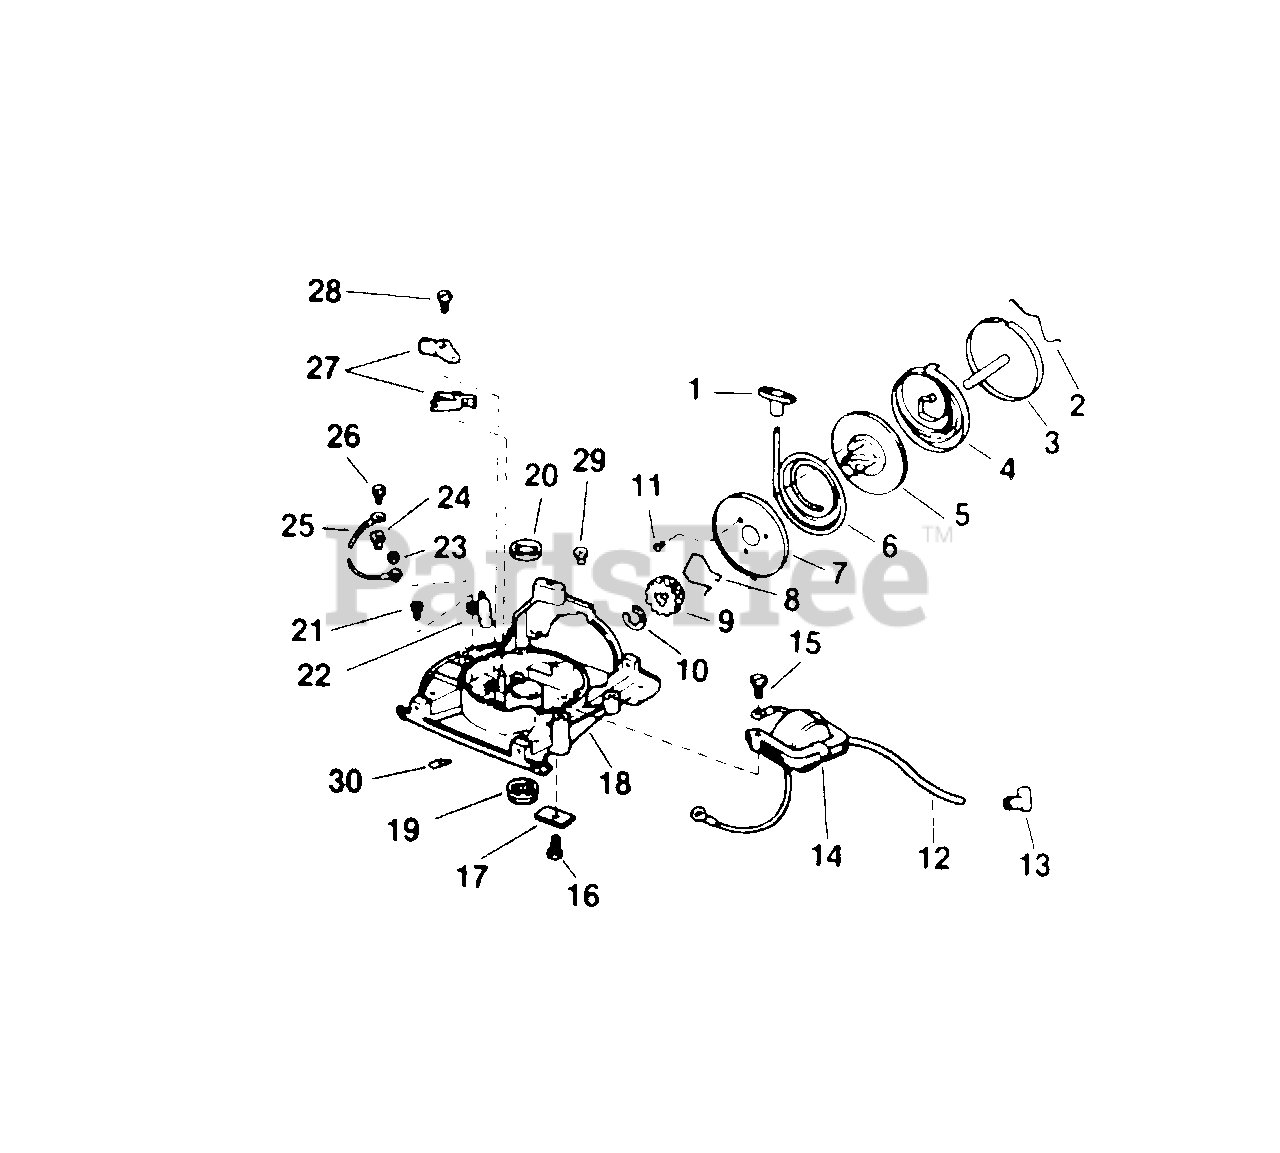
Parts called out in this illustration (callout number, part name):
1	Handle-Starter
2	Spring-Starter Rope Retainer
3	Spring-Cup-Pin Assy.
4	Spring-Starter
5	Pulley-Starter
6	Rope-Starter
7	Plate-Starter Pulley
8	Spring-Starter Pinion
9	Pinion-Starter
10	Retainer-Push-On
11	Screw-Threaded Cutting Starter
12	High Tension Lead Assy.
13	Cover and Terminal Assy.
14	Coil & Lamination Assy.
15	Screw-Lamination Mtg.
16	Screw-Starter Attach.
17	Clamp-Starter Pin
18	Arm. Pl., Brg. & Oil Seal Assy.
19	Bearing
20	Oil Seal
21	Screw-Cond. Mtg.
22	Cond. & Nut Assy.
24	Grommet-Nylon
25	Terminal & Lead Assy.
26	Screw-Shut-Off Sw.
27	Brkr. Base & Arm Assy.
28	Screw-Breaker Base
29	Grommet
